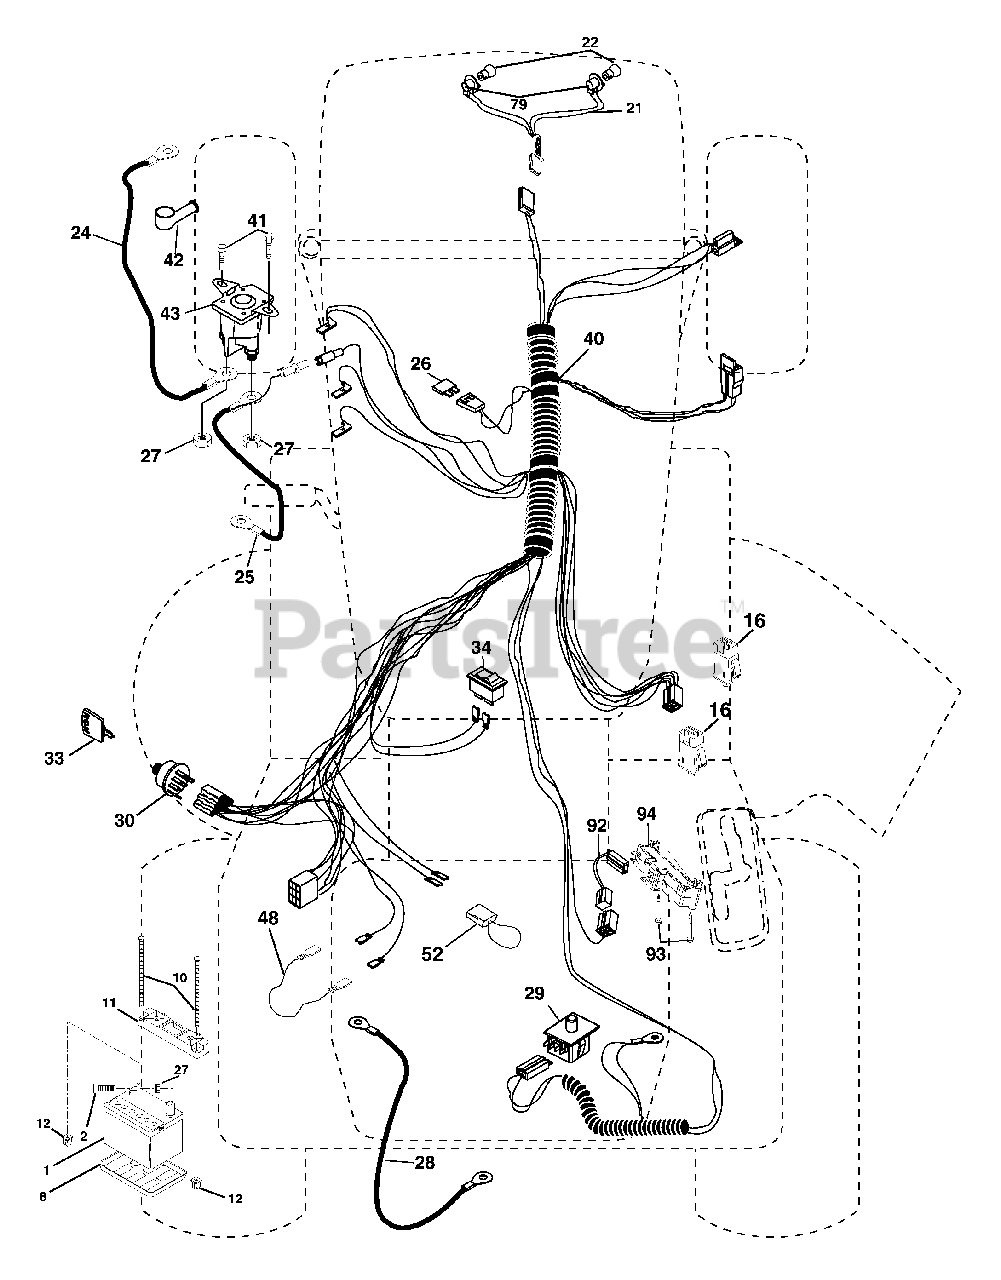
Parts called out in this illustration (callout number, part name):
2	Bolt Hex Hd 1/4-20 unc x 3/4
8	Tray Battery
10	Bolt Battery Front1/4-20 x 7.5
11	Hold Down Battery Front Mount
12	Nut Push Nylon 1/4"Battery Front
16	Switch Interlock
21	Harness Socket Light
22	Bulb, Light # 1156
24	Cable Battery
25	Cable Battery
26	Fuse
27	Nut Keps Hex 1/4-20 unc
28	Cable Ground
29	Switch
30	Switch Ign
33	Key Ign Molded Generic
34	Switch Light/Reset
40	Harness Ign
41	Screw Thd Cut 1/4-20 x 1/2
42	Cover Terminal Red
43	Solenoid
48	Ammeter Adapter
52	Protection Loop
55	Screw Thd Cut 5/16-18 x 1/2
79	Socket Asm
90	Cover Terminal
92	Harness Pigtail Reverse Switch
93	Screw Plastite 10-14 x 2.0
94	Module Reverse ROS
